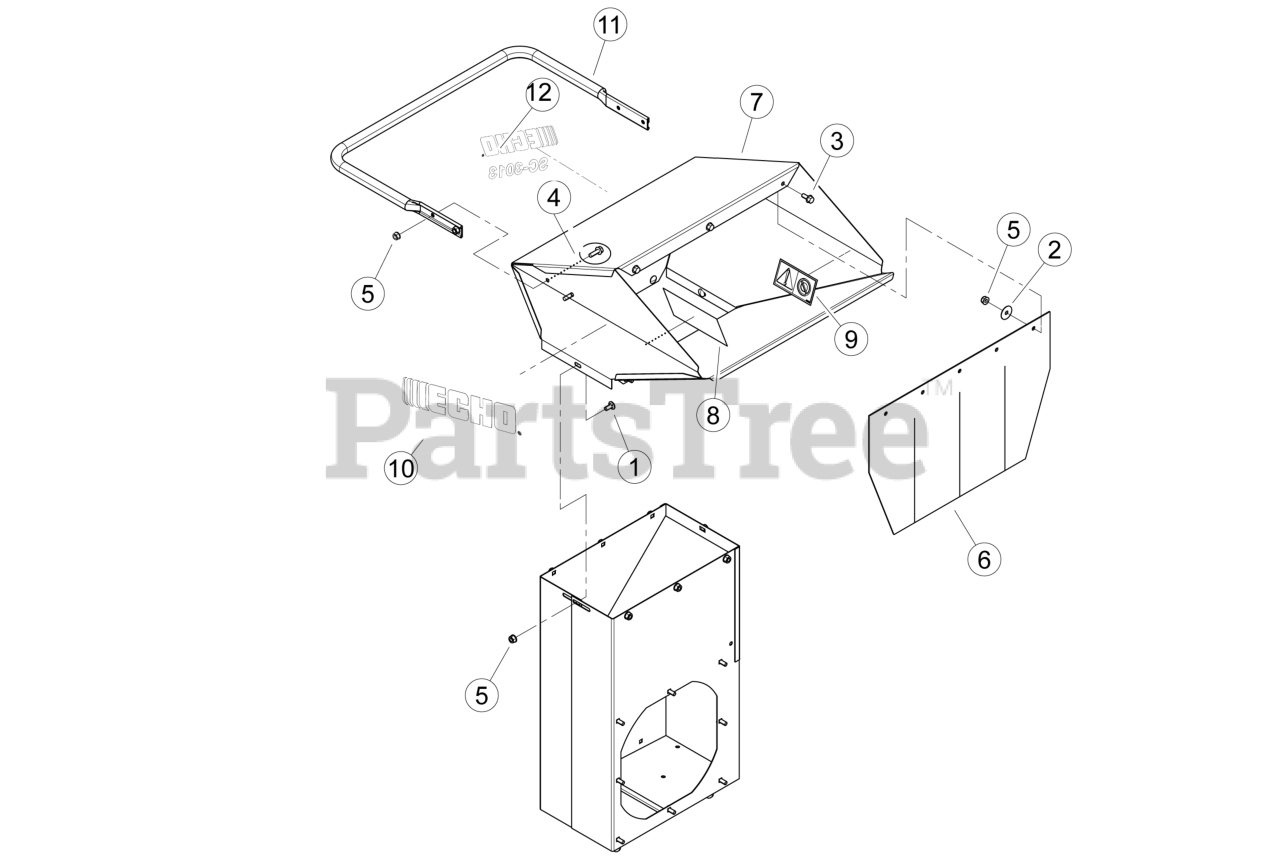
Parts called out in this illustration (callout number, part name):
1	BOLT, 5/16-18 × 3/4 SN GR5 CRG
2	WASHER, 5/16" FENDER ZP
3	BOLT, 5/16 × 3/4 FLANGE NC
4	BOLT, 5/16 × 1 FLANGE NC
5	NUT, 5/16-18 NYLOCK FLANGE
6	BELTING, RENTAL HOPPER
7	ASSEMBLY, WIDE BODY RENTAL HOPPER W/ DECALS
8	DECAL, BLADE DANGER ISO
9	DECAL, SHREDDER SIZE ISO
10	DECAL, ECHO
11	HANDLE, RENTAL HOPPER
12	DECAL, MODEL SC-3013
